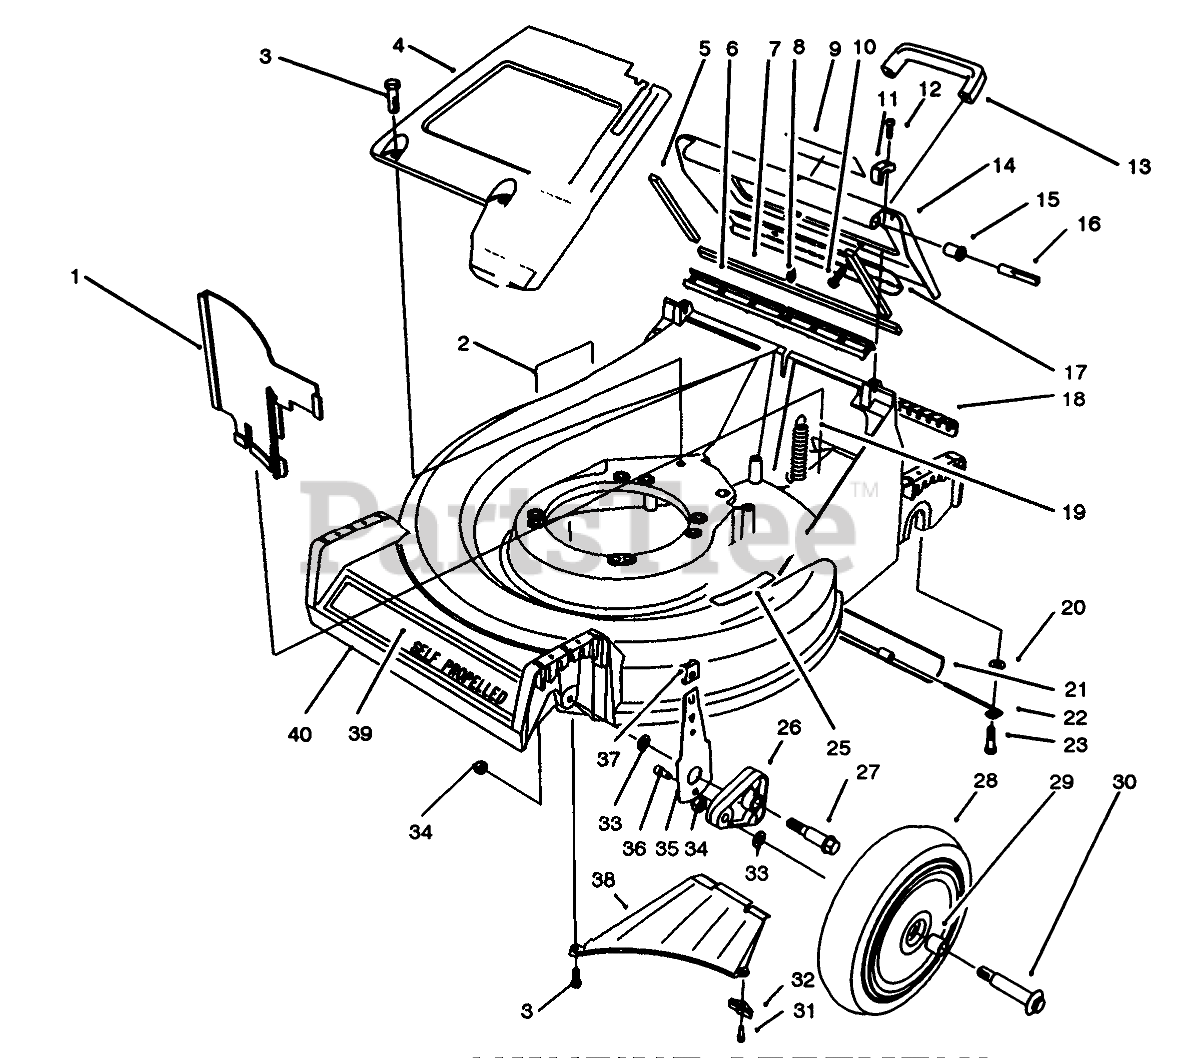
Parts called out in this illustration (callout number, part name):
1	PANEL-VERTICAL
2	DECAL-DANGER
3	SCREW-HWHTF
4	PaneI-Screen
5	DOOR SIDE SEAL
6	DOOR SEAL
7	DOOR END SEAL
8	DOOR CABLE
9	DECAL - DANGER
10	SCREW-HWH
11	HINGE CLAMP
12	SCREW-HSH
13	HANDLE-DOOR
14	Door-Discharge (Incl. Ref. #5, 7, 9, &17)
15	DOOR BUSHING
16	HINGE PIN
17	DOOR - BRACE
18	ACCESS COVER
19	EXTENSION-SPRING
20	WASHER-PLAIN
21	TRAILING SHIELD
22	SHIELD HANGER
23	SCREW-SHOULDER
25	DECAL - STEP PAD INT'L
26	ARM-PIVOT, FRONT
27	BOLT-SHOULDER
28	Wheel & Tire Assembly (Incl. Ref. #29)
29	BUSHING
30	WHEEL BOLT
31	SCREW-HWHTF
32	Bracket-Discharge
33	WASHER
34	NUT-LOCK
35	FRONT SPRING ARM ASM
36	SCREW-HSH, THREAD FORMING
37	KNOB-ARM
38	Ramp Discharge
39	DECAL _ 21"
40	Housing-Deck (Incl. Ref. #2 & 25)
